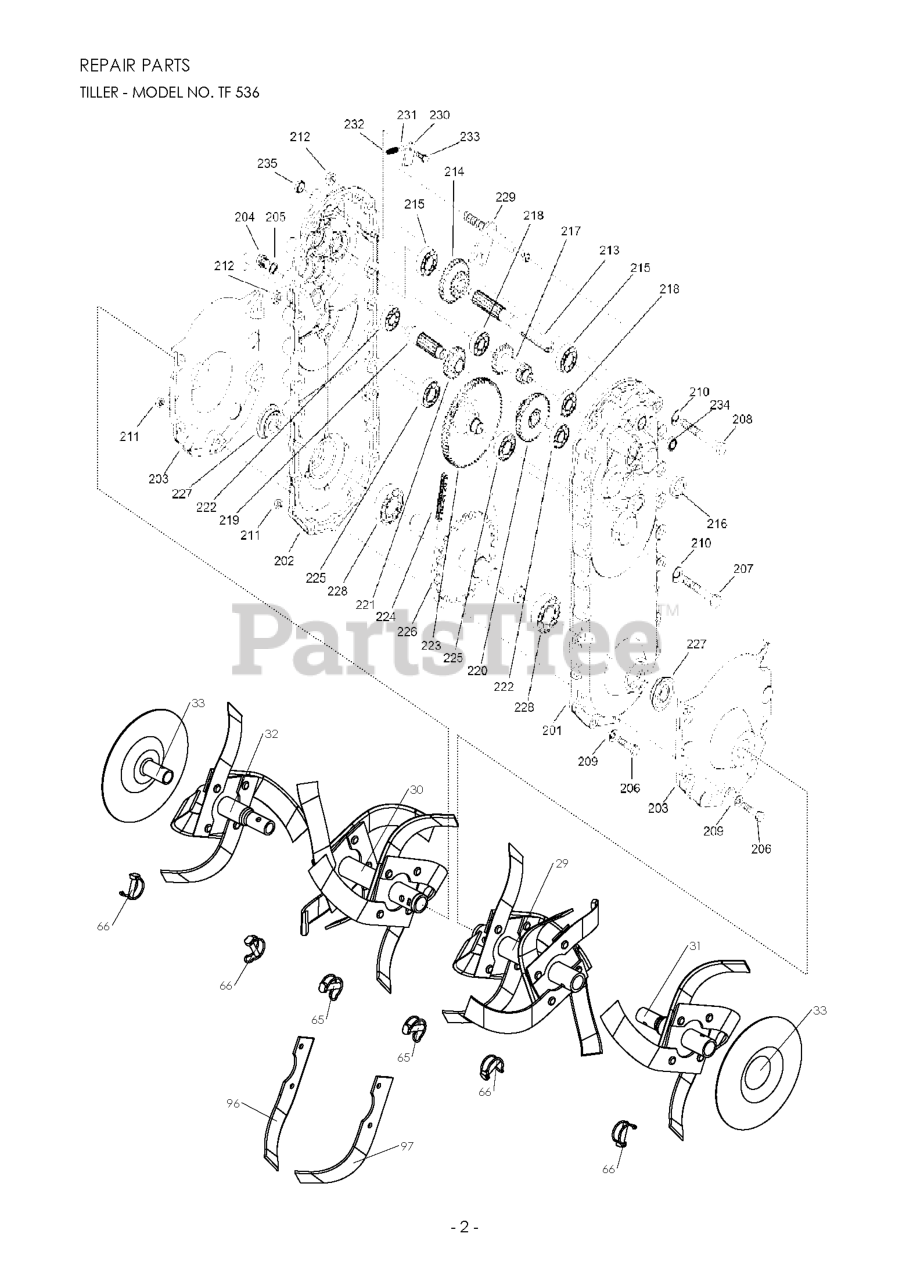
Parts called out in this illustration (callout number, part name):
215	BALL BEARING 0002010226
225	BALL BEARING 0002010226
228	BALL BEARING 6205
232	SPRING 0002010237
